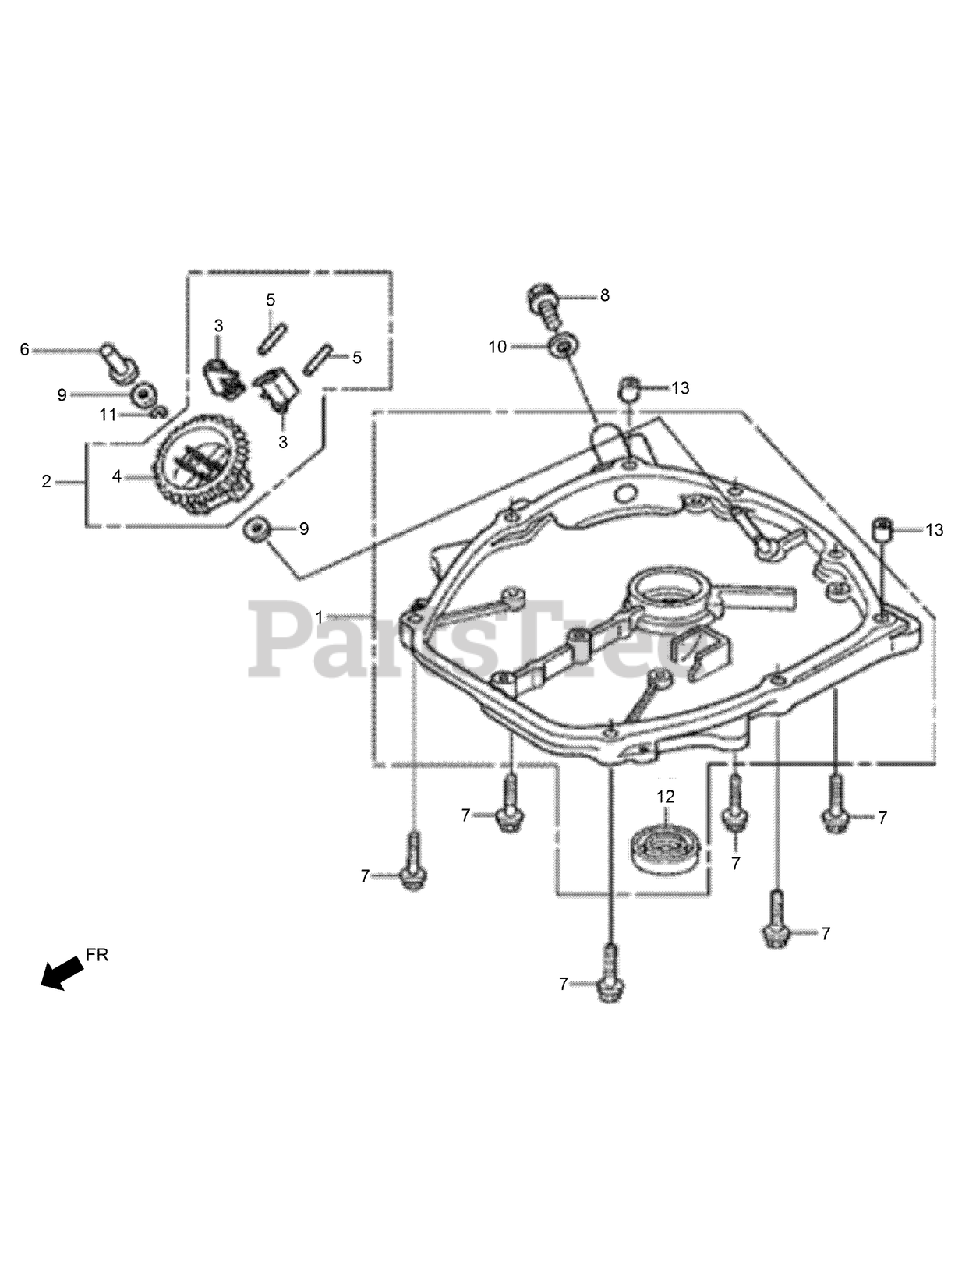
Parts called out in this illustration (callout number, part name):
1	CRANKCASE SIDE COVER ASM
2	GOVERNOR ASM
3	WEIGHT-GOVERNOR
4	HOLDER-GOVERNOR WEIGHT
5	PIN-GOVERNOR WEIGHT
6	SLIDER-GOVERNOR
7	BOLT-FLANGE-5X23
8	BOLT-DRAIN PLUG-12X15
9	WASHER-4.2X13
10	WASHER-DRAIN PLUG-12MM
11	CLIP-GOVERNOR HOLDER
12	OIL SEAL-18.9X28X5
13	DOWEL PIN-6X10
